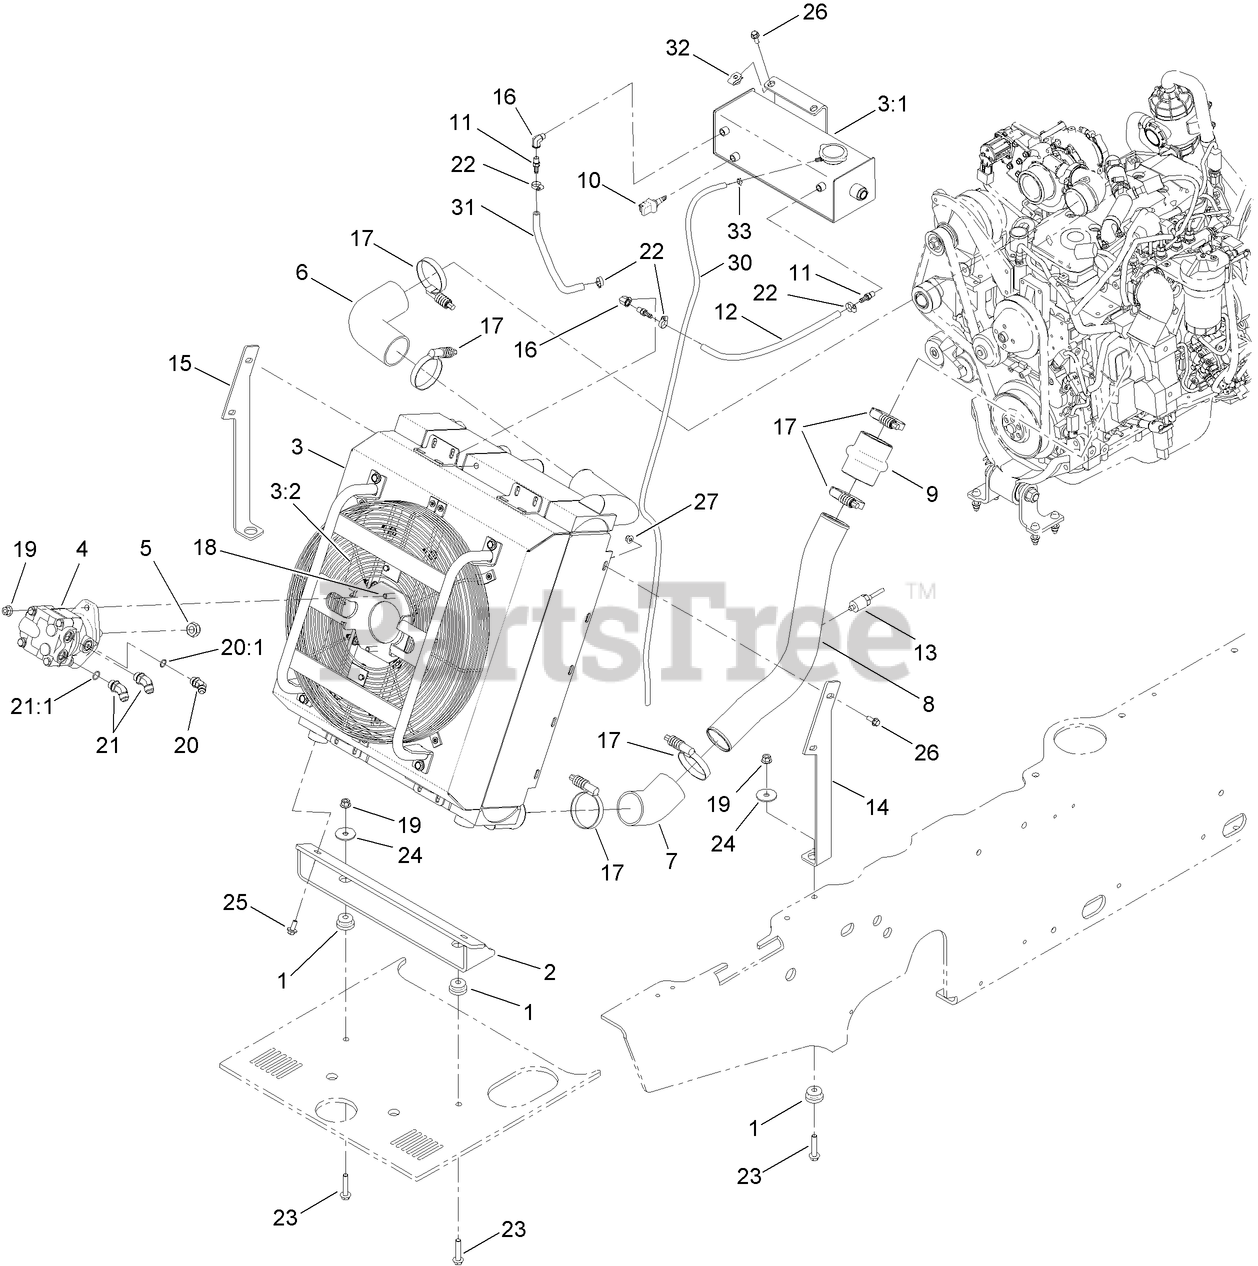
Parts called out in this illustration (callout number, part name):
1	ISOLATOR-MOUNT, RUBBER
2	PLATE-MOUNT, RADIATOR
3	COOLING PACKAGE ASM
3:1	COOLANT RECOVERY TANK ASM
3:2	FAN-COOLING, 22 INCH
4	HYD MOTOR ASM
5	NUT-LOCK, NI
6	ELBOW-COOLER, AIR
7	ELBOW-COOLER, AIR
8	TUBE ASM
9	ADAPTER-HUMP
10	SENSOR-LEVEL, COOLANT
11	FITTING-STRAIGHT
12	HOSE-COOLANT
13	TRANSDUCER-TEMPERATURE
14	BRACKET-COOLING, LH
15	BRACKET-COOLING, RH
16	FITTING-ELBOW, 90
17	CLAMP-TORQUE, CONSTANT
18	SCREW-HHF
19	NUT-LOCK, HHF
20	FITTING-ELBOW, 45 DEG
20:1	O-RING
21	FITTING-ELBOW-45 DEG
21:1	O-RING
22	CLAMP-HOSE
23	SCREW-HHF
24	WASHER-FLAT
25	SCREW-HHF
26	SCREW-HHF
27	NUT-HEX FLG
30	HOSE-COOLANT
31	HOSE-COOLANT
32	NUT-CLIP, U
33	CLAMP-HOSE
